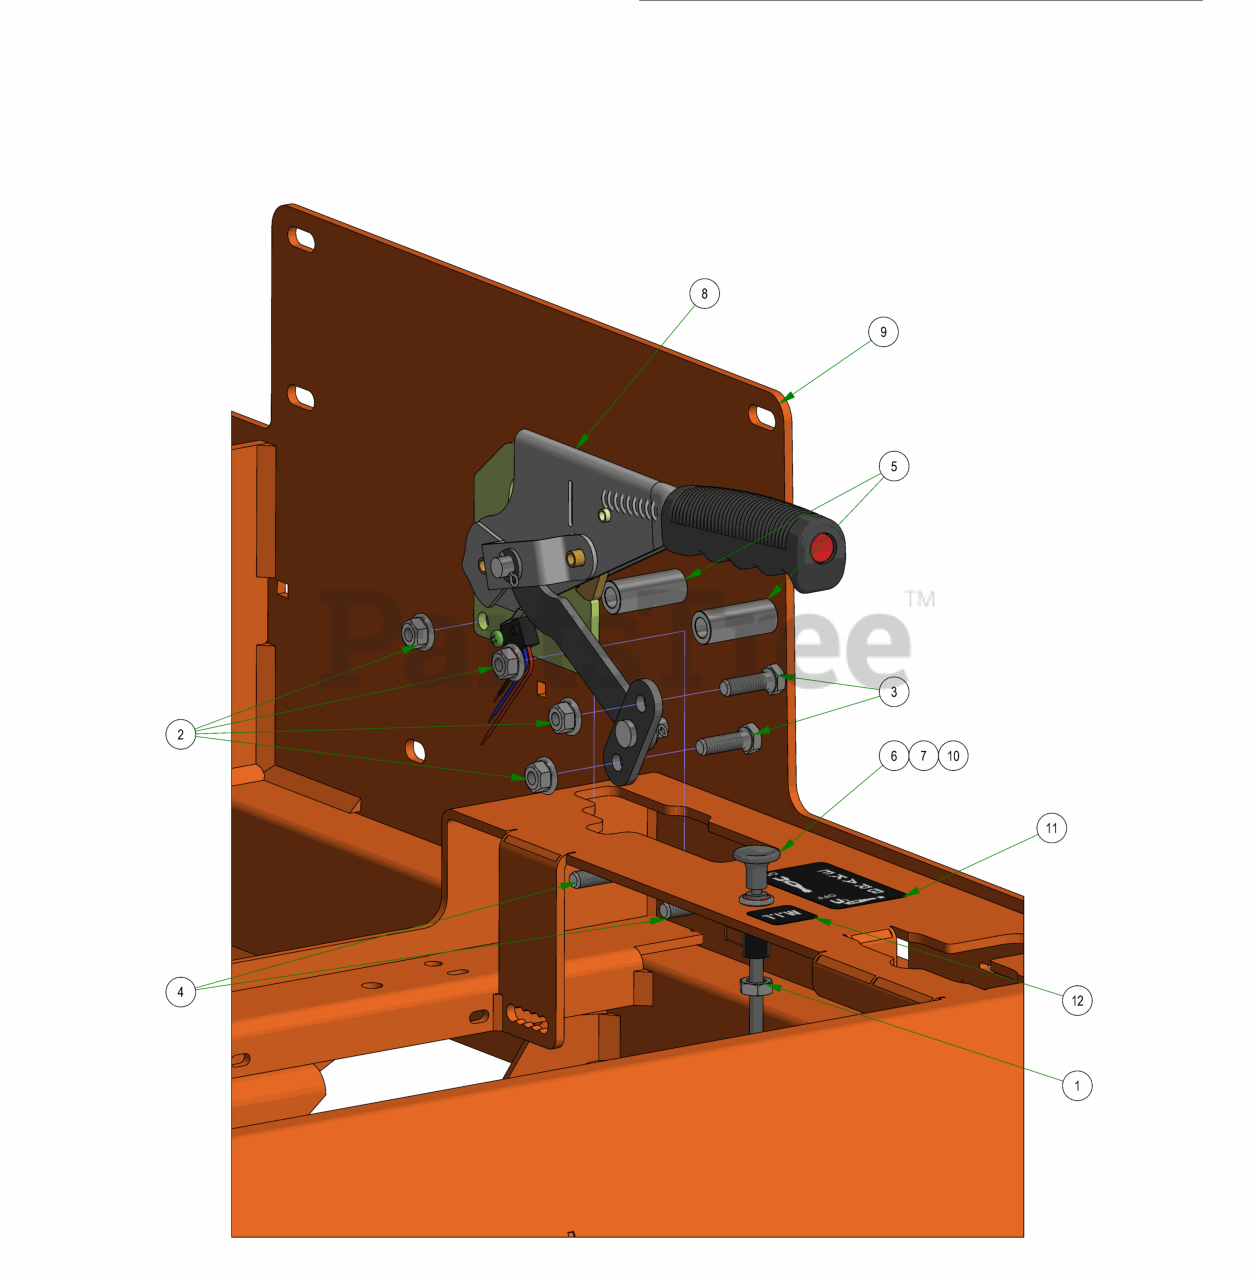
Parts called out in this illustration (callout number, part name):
1	3/8-24 HEX NUT ZINC YELLOW
2	5/16-18 NYLON INSERT FLANGE LOCKNUT ZINC
3	5/16-18 X 1 HEX CAP SCREW (GR.5) ZINC
4	5/16-18 X 2-1/2 HEX CAP SCREW (GR.5) ZINC
5	.380 ID X .625 OD X 1.500 LGTH 2019 OUTLAW BRAKE HANDLE SPACER ZINC
7	Choke for 36Hp Vanguard & FX1000 Kawasaki
8	2019 Brake Handle Assembly
9	2023 Rogue Frame - Painted
10	Code Indicator Light
11	2018 Out/XP/Diesel Brake Decal
12	2019 MIL Decal For Rogue EFI Models
